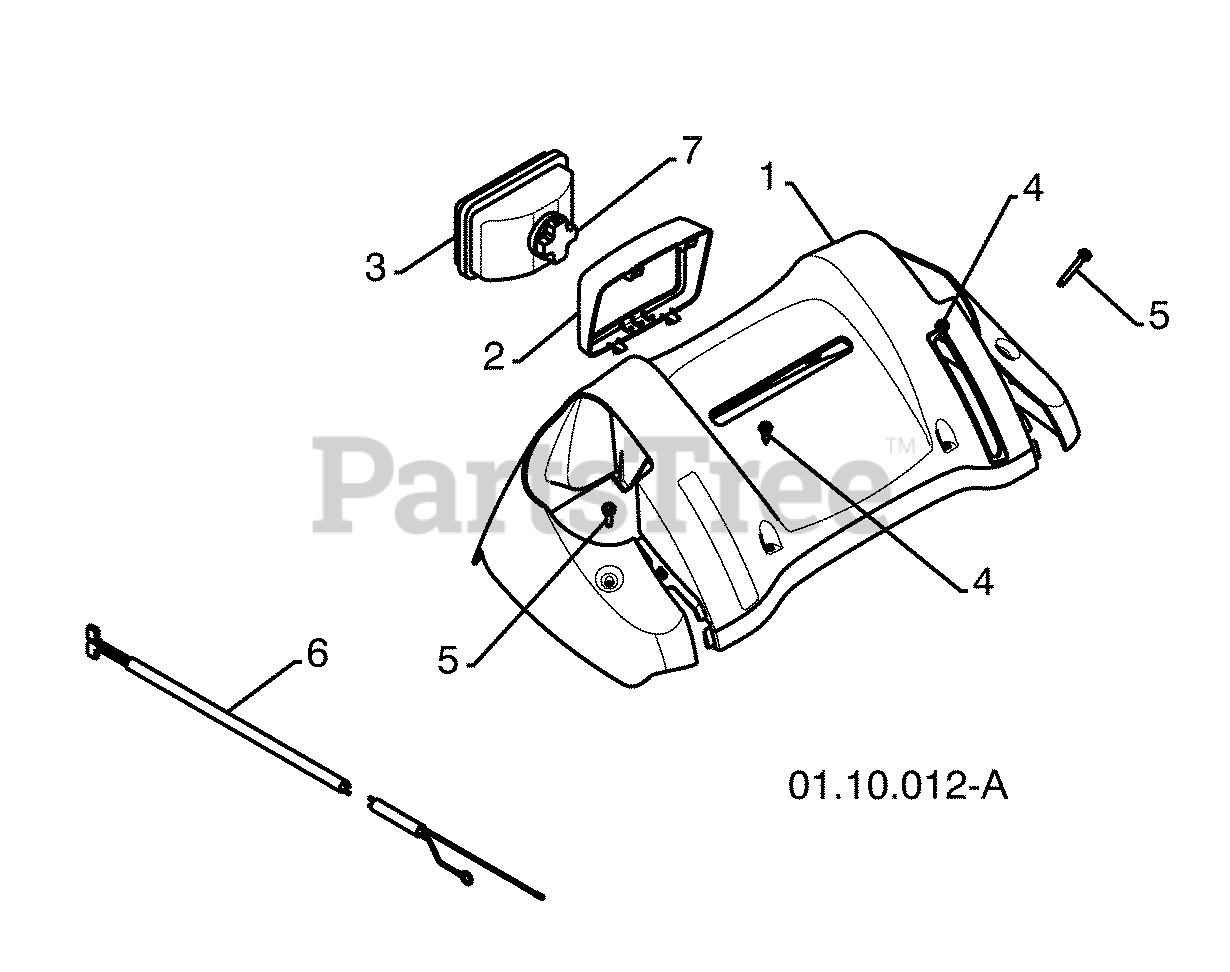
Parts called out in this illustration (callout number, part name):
1	CONSOLE PANEL GRAY
2	HEADLIGHT BEZEL GRAY
3	FLOOD HEADLIGHT
4	SHOULDER SCREW 10--24 X .625
5	SCREW 10--24 X 1.25
6	WIRE HARNESS
